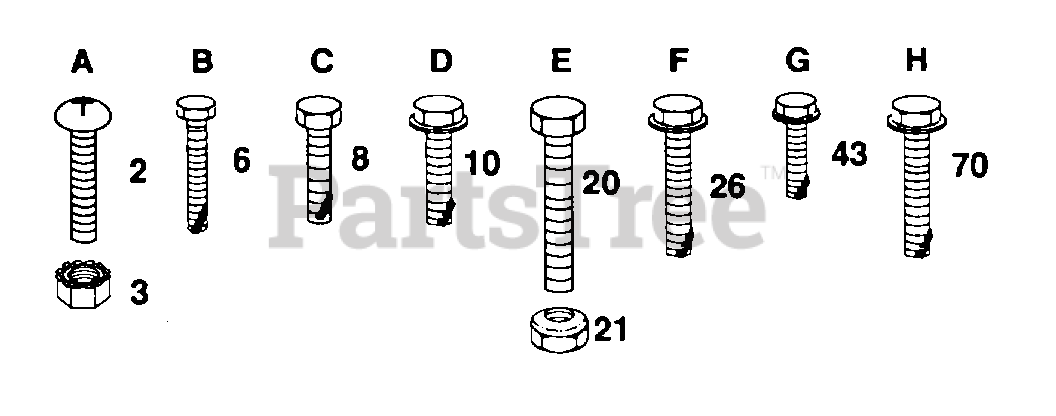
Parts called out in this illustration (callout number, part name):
2	SCREW
6	SCREW LT
10	SCREW LT
26	SCREW
43	SCREW LT
70	SCREW SPECIAL
